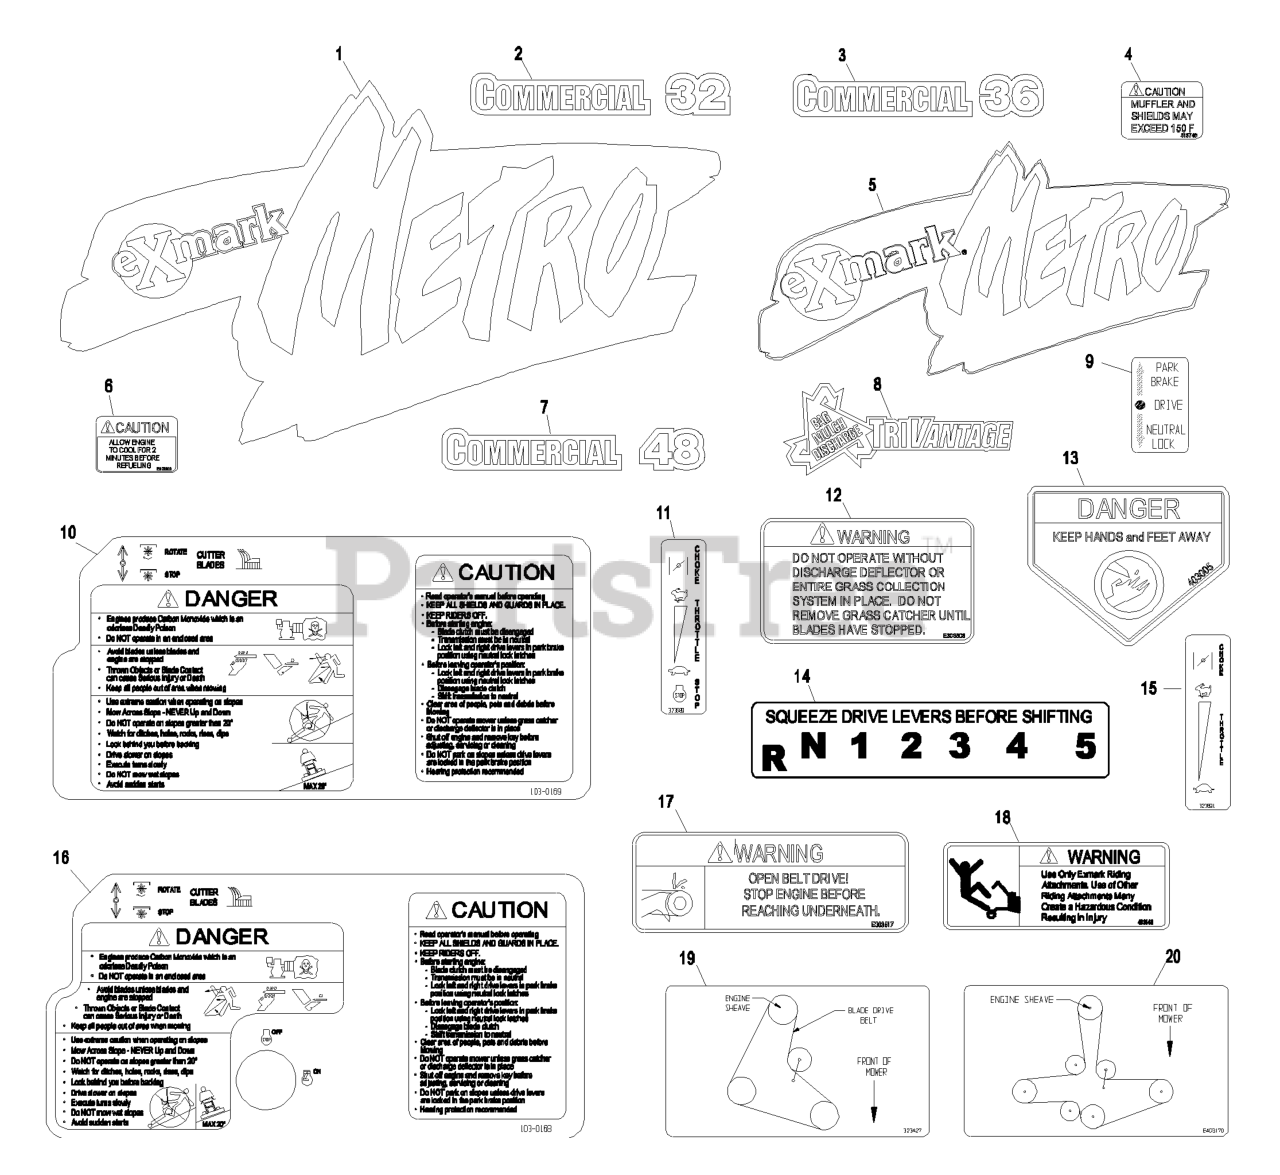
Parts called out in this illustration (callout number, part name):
2	DECAL,COMMERCIAL 32
3	DECAL,COMMERCIAL 36
7	DECAL,COMMERCIAL 48
9	DECAL,NEUTRAL/BRAKE
12	DECAL-WARNING, DISCHARGE
13	DECAL-DANGER
14	DECAL,SHIFTER
15	DECAL,THROTTLE
17	DECAL,BELT DRIVE
18	DECAL,SULKY WARNING
19	DECAL,BELT ROUTING 32/36
